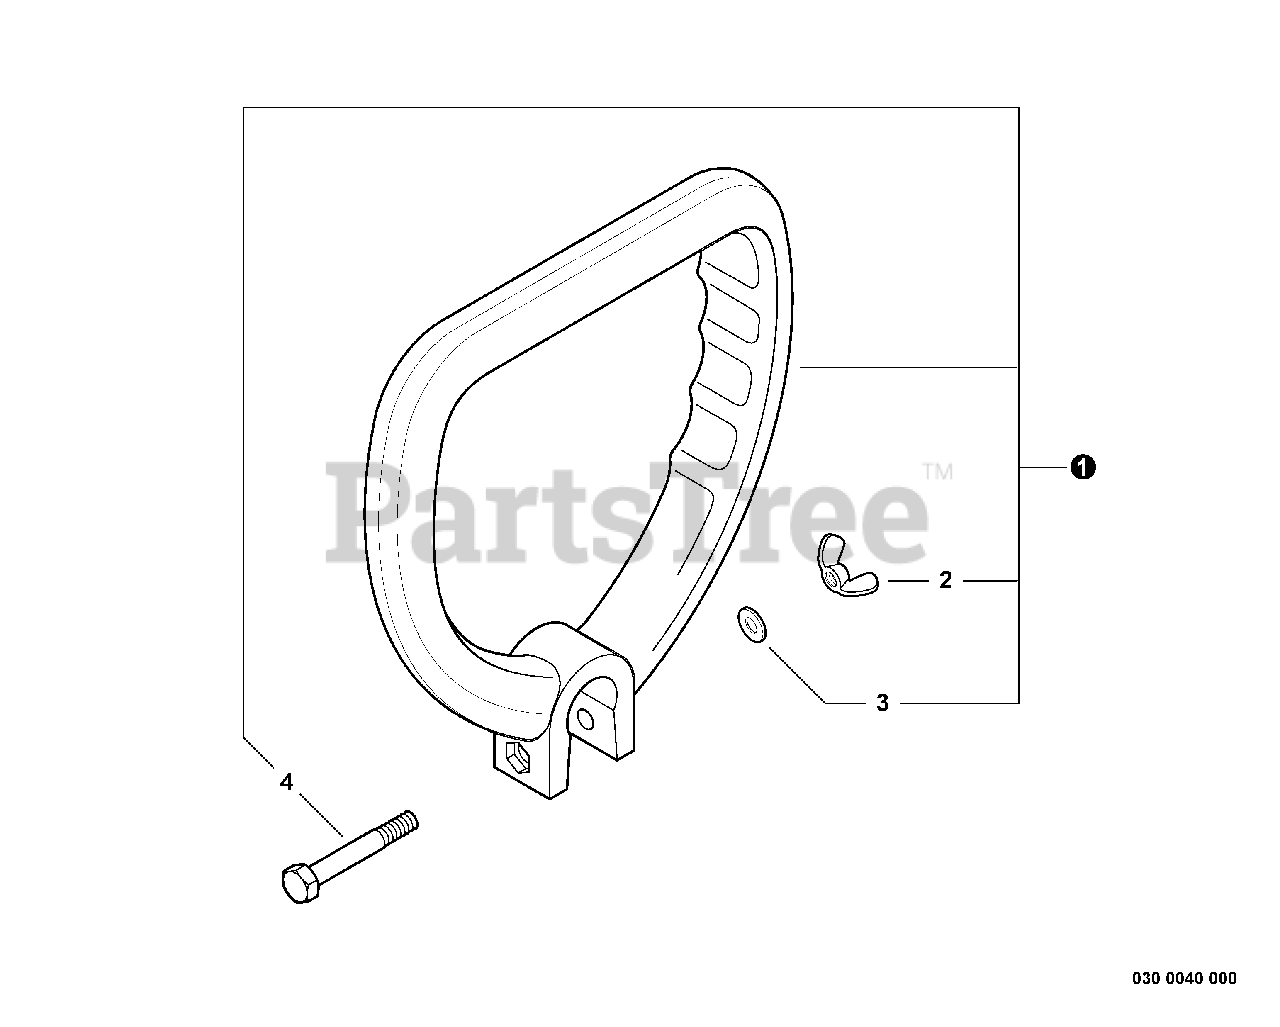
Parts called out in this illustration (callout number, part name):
1	HANDLE ASSY - FRONT
2	WINGNUT - 1/4-20
3	WASHER - 1/4"
4	BOLT - 1/4-20 X 1-1/2"
